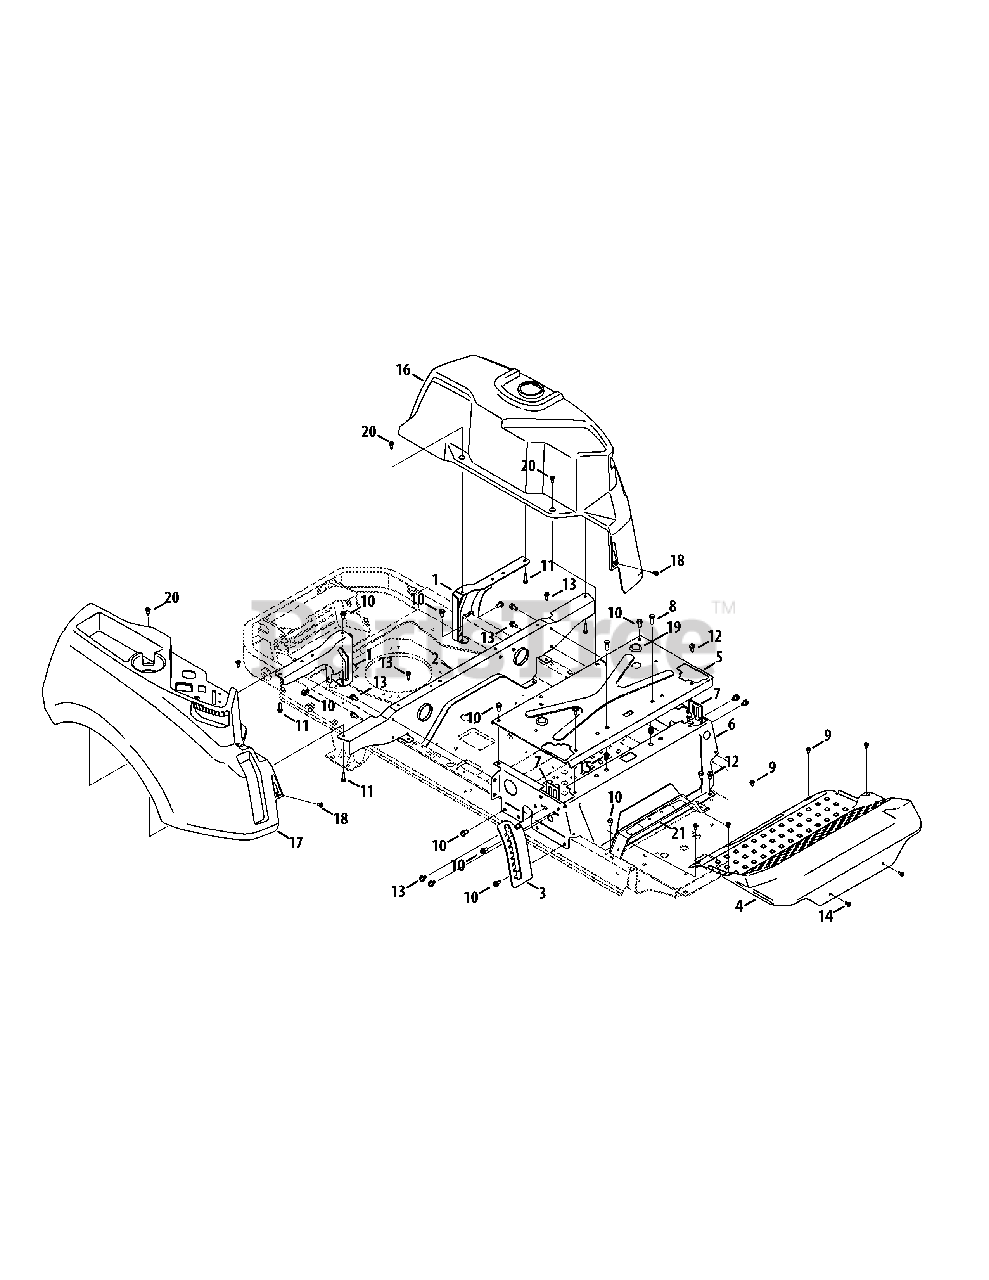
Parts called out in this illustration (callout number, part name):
1	Rear Tank Bracket
2	Rear Seatbox Brace
3	Height Index Bracket
4	Floor Board, Fab
5	Seatbox Plate
6	Seat Frame
7	Lapbar Brace Bracket
8	Hex Cap Screw, 5/16-18 x 1.00
9	Self Tapping Screw, 1/4-20 x .50
10	Hex Washer Screw, 5/16-18 x .750
11	Hex Washer Screw, 5/16-14 x 1.00
12	Self Tapping Screw, 5/16-18 x .750
13	Hex Washer Screw, 5/16-18 x .50
14	Screw, Self-Tapping, 5/16-18, 0.750
15	Nut, 5/16-18
16	LH Console
17	RH Console
18	Shoulder Screw, 1/4-20
19	Button Plug
20	Shoulder Screw, .368 x .115, M6-1
21	Steering Support Bracket
